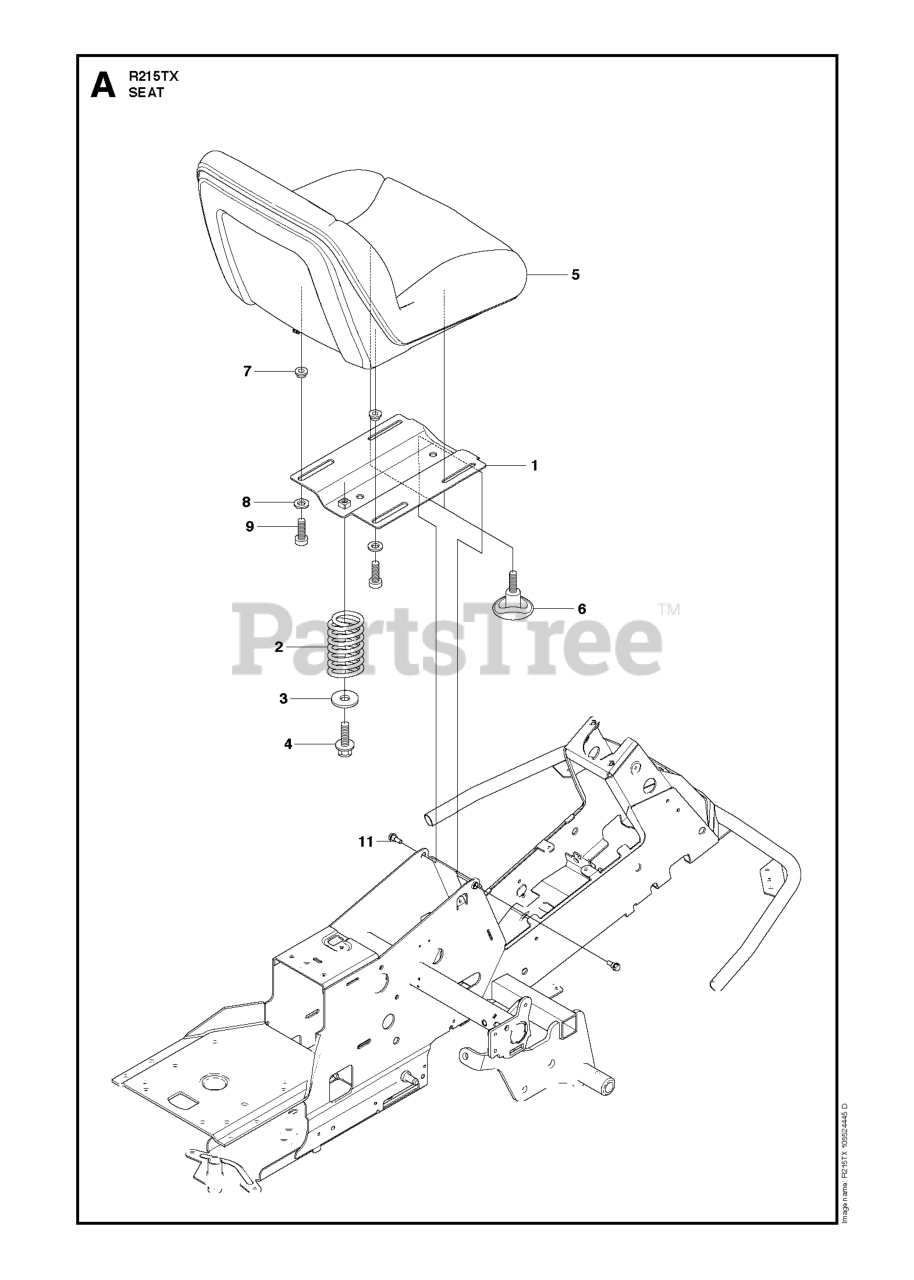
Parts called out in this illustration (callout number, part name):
1	SEAT BRACKET
2	SEAT SPRING
4	Screw M10x25
5	SEAT
6	ADJUSTING KNOB
